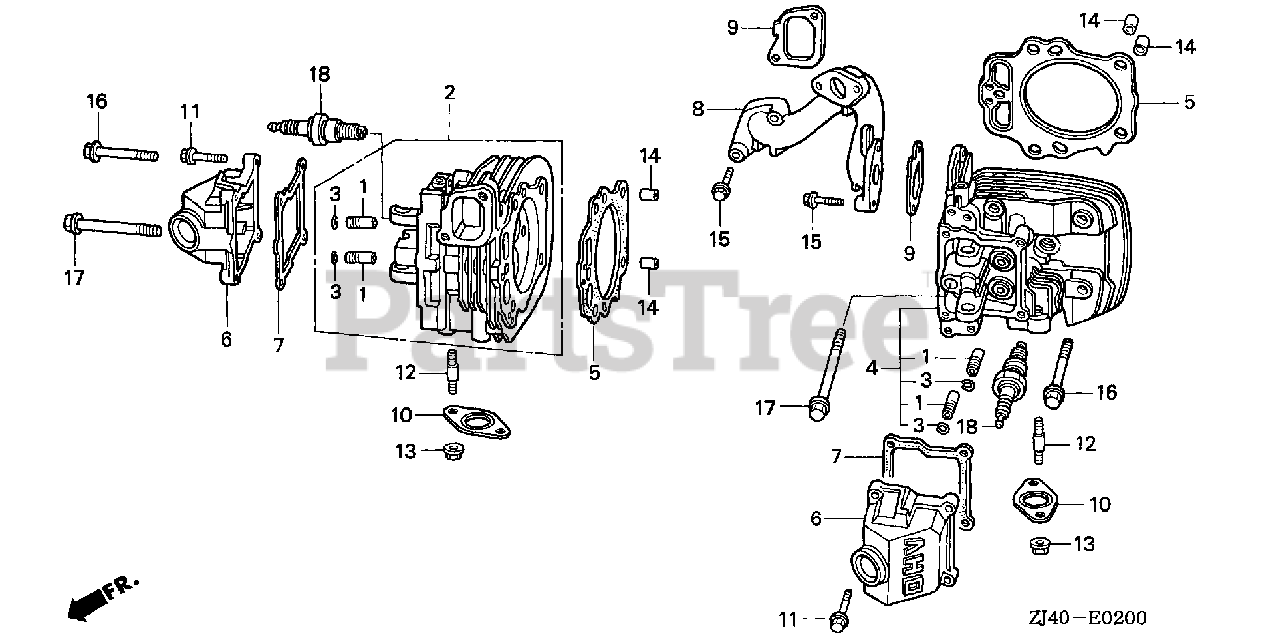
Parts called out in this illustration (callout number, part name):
1	GUIDE, EX. VALVE (OVER SIZE)
2	CYLINDER HEAD (#1)
3	CLIP, VALVE GUIDE
4	CYLINDER HEAD (#2)
5	GASKET, CYLINDER HEAD
6	COVER, HEAD
7	GASKET, HEAD COVER
8	MANIFOLD, IN.
9	GASKET, IN. MANIFOLD
10	GASKET, EX. PIPE
11	BOLT, FLANGE (6X25) (CT200)
12	BOLT, STUD (8X25)
13	NUT, FLANGE (8MM)
14	PIN, DOWEL (12X20)
15	BOLT, FLANGE (6X32)
16	BOLT, FLANGE (10X75)
17	BOLT, FLANGE (10X130)
18	SPARK PLUG (BPR5ES) (NGK)
